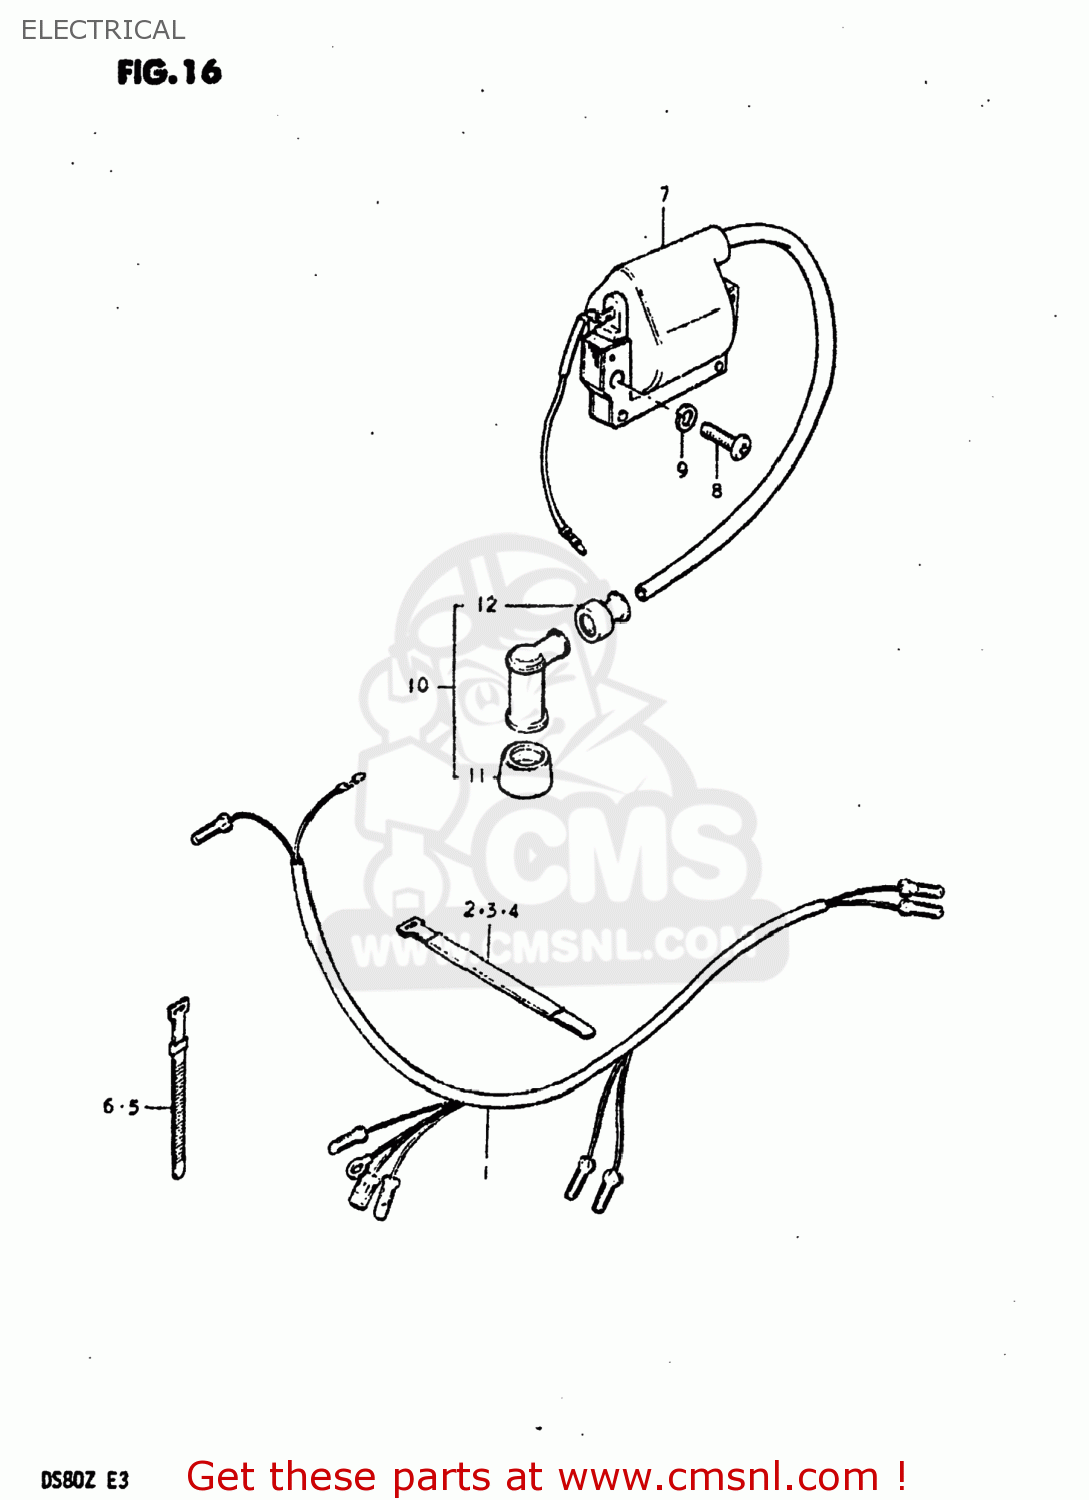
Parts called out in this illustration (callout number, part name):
1	HARNESS,WIRING
2	CLAMP
3	CLAMP L:110
4	CLAMP
5	CLAMP(L:80)
6	CLAMP(L:120)
7	COIL ASSEMBLY,IGNITION
8	SCREW
9	LOCK WASHER
10	CAP,SPARK PLUG
11	SEAL,SPARK PLUG
12	SEAL,SPARK PLU
